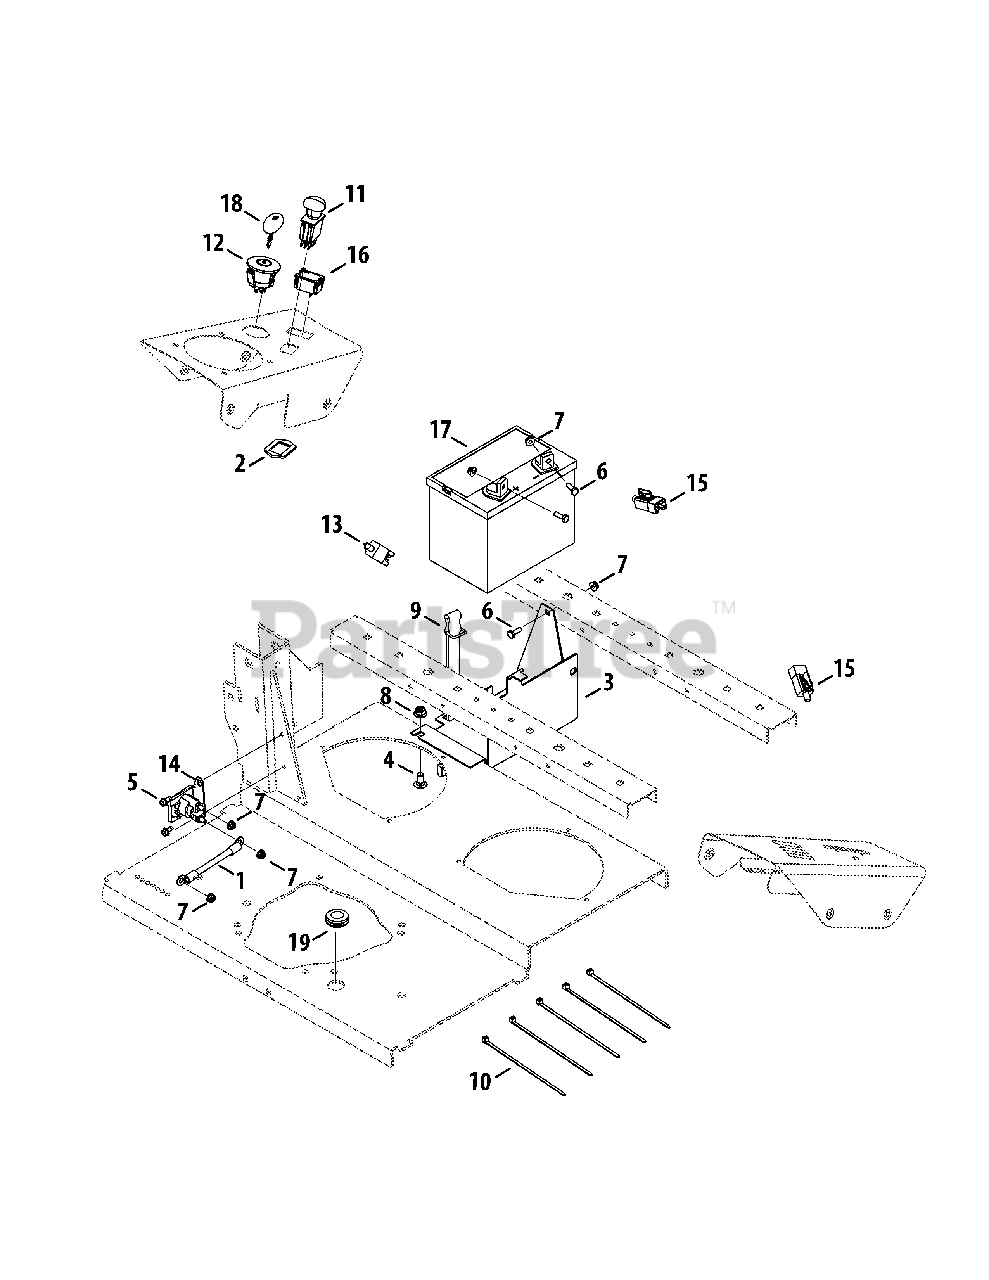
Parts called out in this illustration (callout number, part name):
1	Battery Cable, Red
2	PTO Switch Bracket
3	Battery Bracket
4	Carriage Bolt, 3/8-16 x .750
5	Hex Flange Screw, 1/4-20 x .500
6	Hex Cap Screw, 1/4-20 x .75
7	Nut, 1/4-20, Flangelock
8	Nut, 3/8-16, Flangelock
9	Battery Strap
10	Cable Tie
11	Electric PTO Switch
12	Key Switch
13	Switch, NC/NO/NO
14	Solenoid
15	Plunger Switch, NO/NC
16	Hour Meter
18	Key
19	Rubber Grommet, .75 x 1.062 x .50
